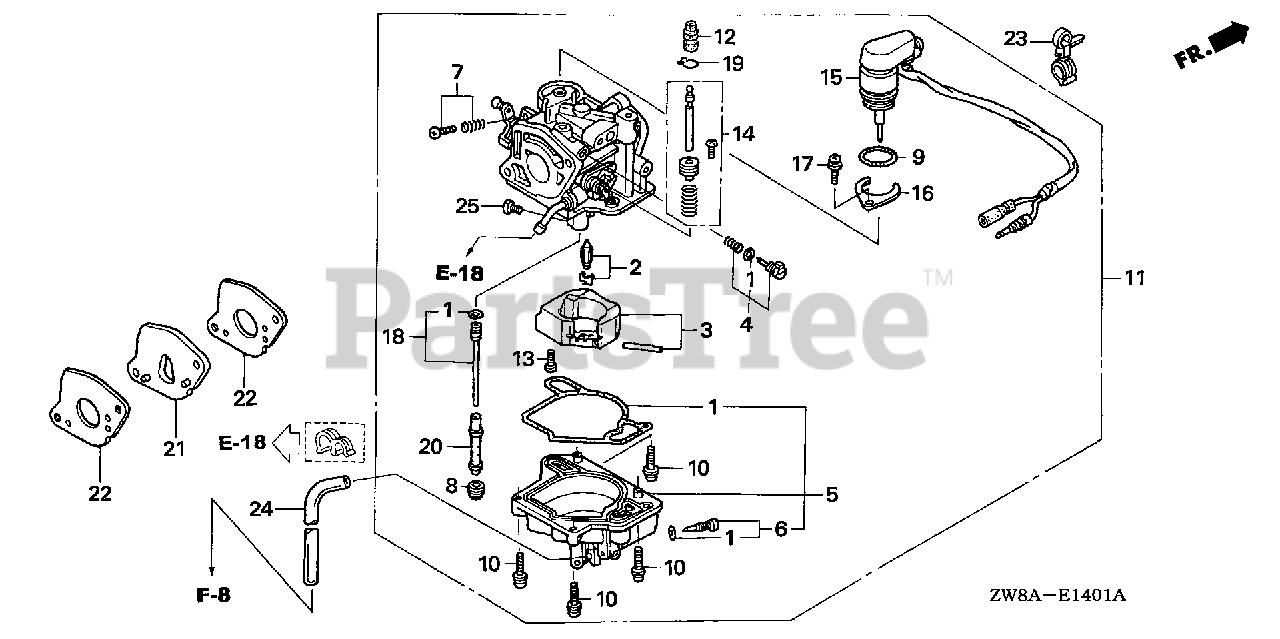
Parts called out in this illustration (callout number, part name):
1	GASKET SET
2	VALVE SET, FLOAT
5	CHAMBER SET, FLOAT
6	SCREW SET, DRAIN
7	SCREW SET
8	SCREW, PLUG
9	O-RING, BYSTARTER
10	SCREW-WASHER
11	CARBURETOR ASSY. (BJ05B D)
13	SCREW, PAN
14	PLUNGER SET, ACCELERATOR PUMP
15	BYSTARTER ASSY., AUTO
16	PLATE, SETTING
17	SCREW-WASHER
18	JET SET (#45)
19	CLIP, TUBE
20	NOZZLE, MAIN
21	INSULATOR, CARBURETOR
22	GASKET, CARBURETOR
23	CLIP, TUBE (135MM) (BLACK)
24	BULK HOSE, VINYL (4X7X8000) (4X7X200)
25	JET, MAIN (#100)
25	JET, MAIN (#102)
25	JET, MAIN (#105)
